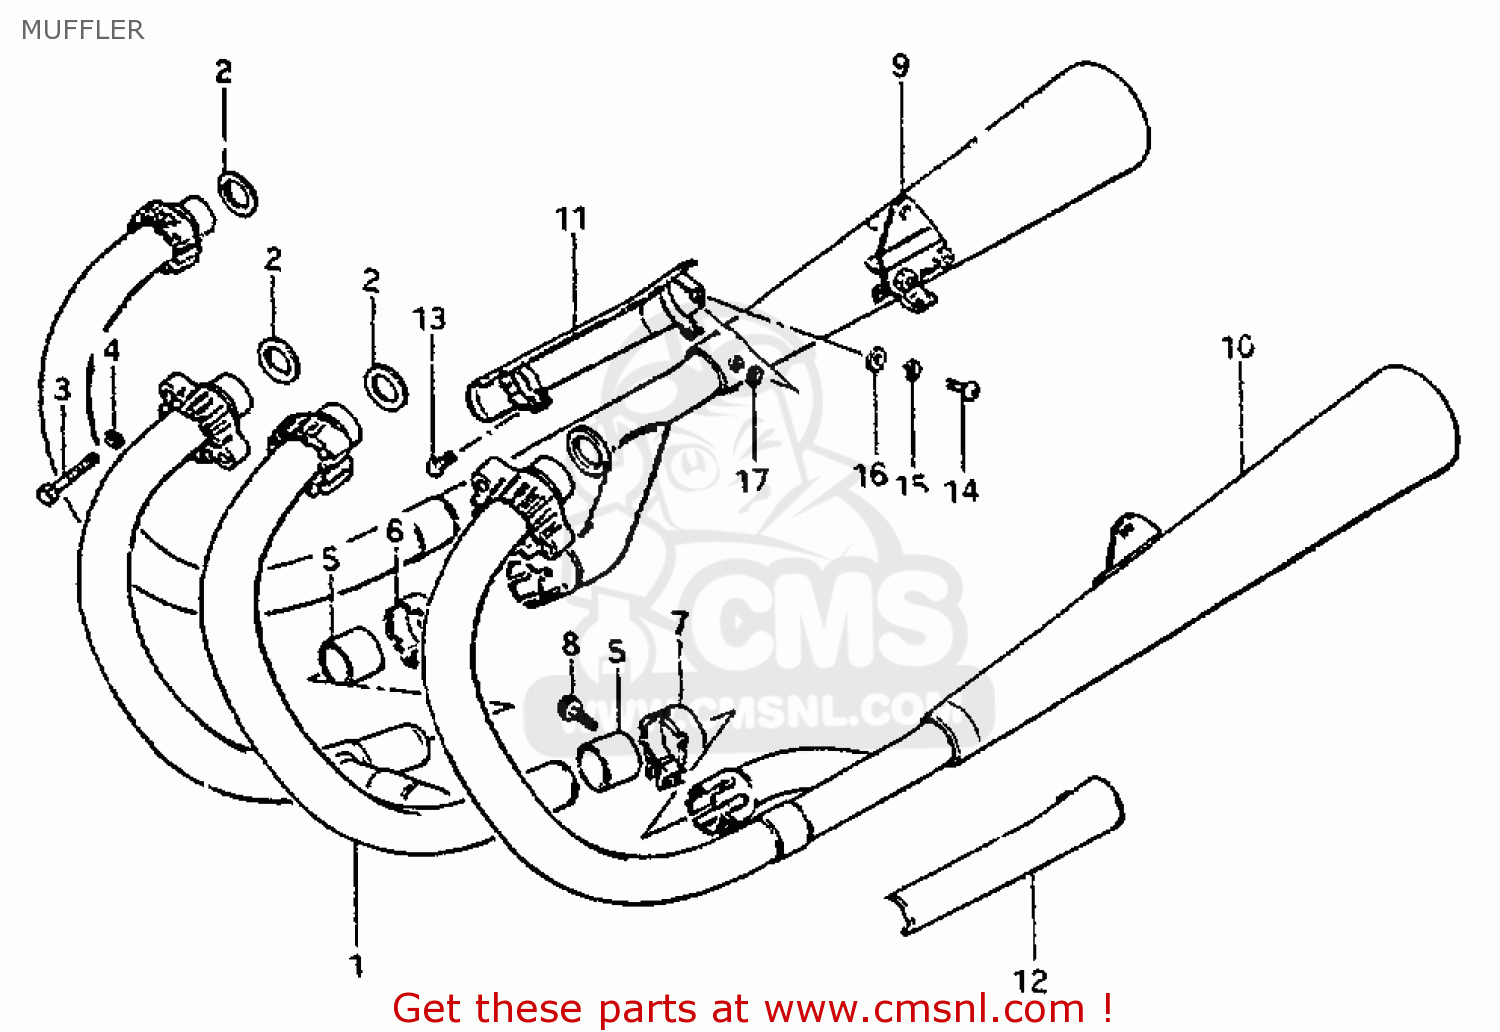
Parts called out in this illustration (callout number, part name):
1	PIPE,EXHAUST,CENTER
2	GASKET,EXHAUST PIPE (NAS)
3	BOLT
4	LOCK WASHER
5	CONNECTOR,MUFFLER
6	CLAMP,MUFFLER CONNECTOR,R
7	CLAMP,MUFFLER CONNECTOR,L
8	BOLT
9	MUFFLER ASSEMBLY
10	MUFFLER, LH
11	COVER,MUFFLER
12	COVER,MUFFLER
13	SCREW
14	SCREW 6X12
15	LOCK WASHER
16	WASHER
17	GASKET 6.2X12X1.5 (MCA)
